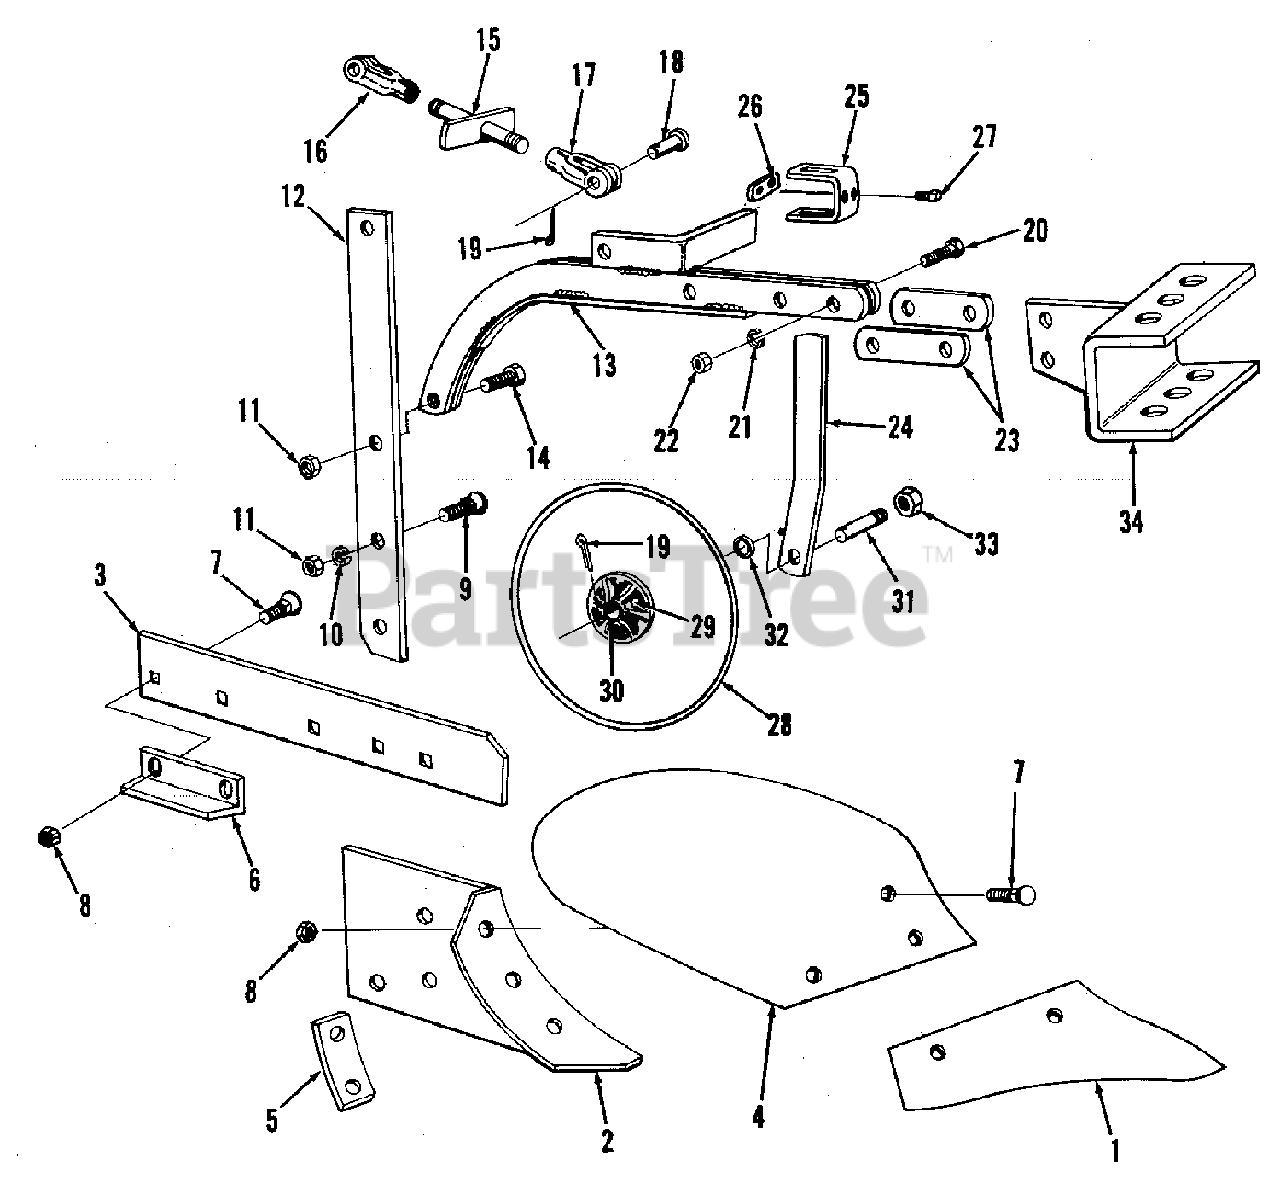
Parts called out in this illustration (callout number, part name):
5	BRACE, Moldboard
6	ANGLE, Slip Heel
7	BOLT, Plow, 7/16-14 x 1-1/4
9	BOLT, Plow, 1/2-13 x 1-1/2
10	WASHER, Lock
11	NUT, Full Hex
13	BEAM ASSEMBLY, Plow
14	SCREW, Hex Cap, 1/2-13 x 1-3/4
15	YOKE, Rod Assembly
20	SCREW, Hex Cap
21	WASHER, Lock
22	NUT, Full Hex
23	SPACER, Plow Beam
24	STANDARD, Coulter
25	SHANK, Clamp
26	NUT, Special
27	SETSCREW, Square Head
28	COULTER ASSEMBLY, W/Bushing
29	FITTING, Grease
31	SPINDLE, Coulter
33	NUT, Hex Jam
34	BEAM, End Assembly
